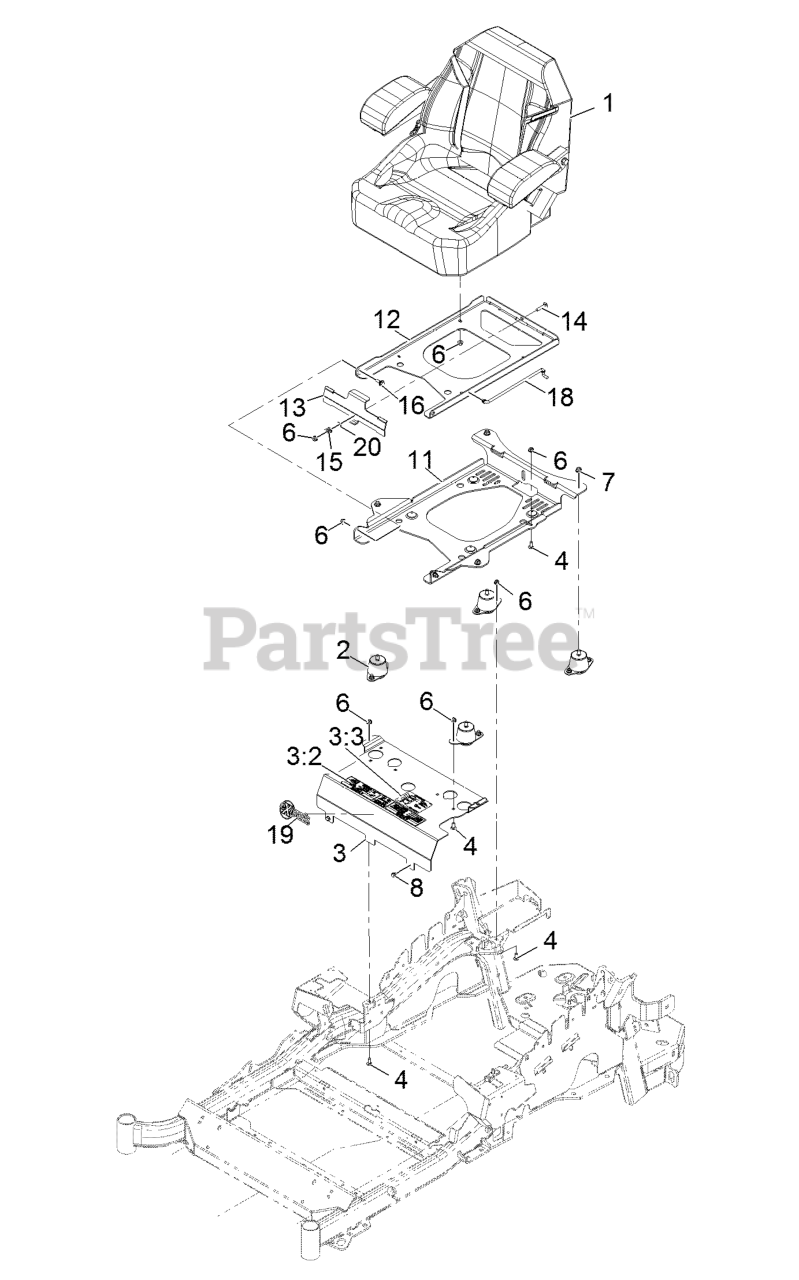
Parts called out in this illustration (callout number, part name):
2	ISOLATOR-SEAT
3	MOUNT-SEAT
3:2	DECAL-CONSOLE
3:3	DECAL-SERVICE AID
4	SCREW-CARR
6	NUT-HF, NI
7	NUT-HF, NI
11	PLATE-TILT, SEAT SUPPORT
12	PLATE-FRAME, SEAT
13	PLATE-LATCH, SEAT
14	BOLT-CARR
15	SPRING-COMPRESSION
16	SCREW-SHOULDER
18	ROD-PROP
20	WASHER-PLAIN
